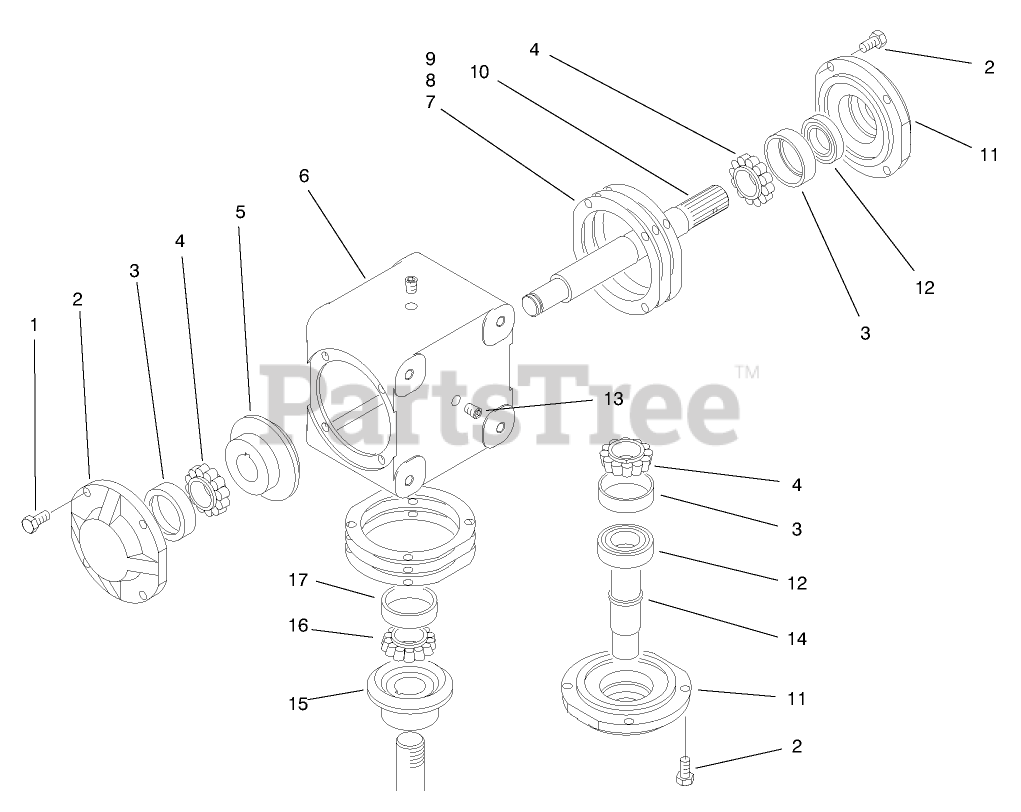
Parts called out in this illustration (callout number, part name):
1	SCREW
3	Cup
4	BEARING - CONE
5	GEAR LH
6	HOUSING
7	GASKET
8	GASKET
9	GASKET
10	SHAFT
11	Cap
12	Seal
13	PLUG (OBS, C/R TO 281-10)
14	SHAFT
15	GEAR RH
16	Bearing Cone
17	Bearing Cup
